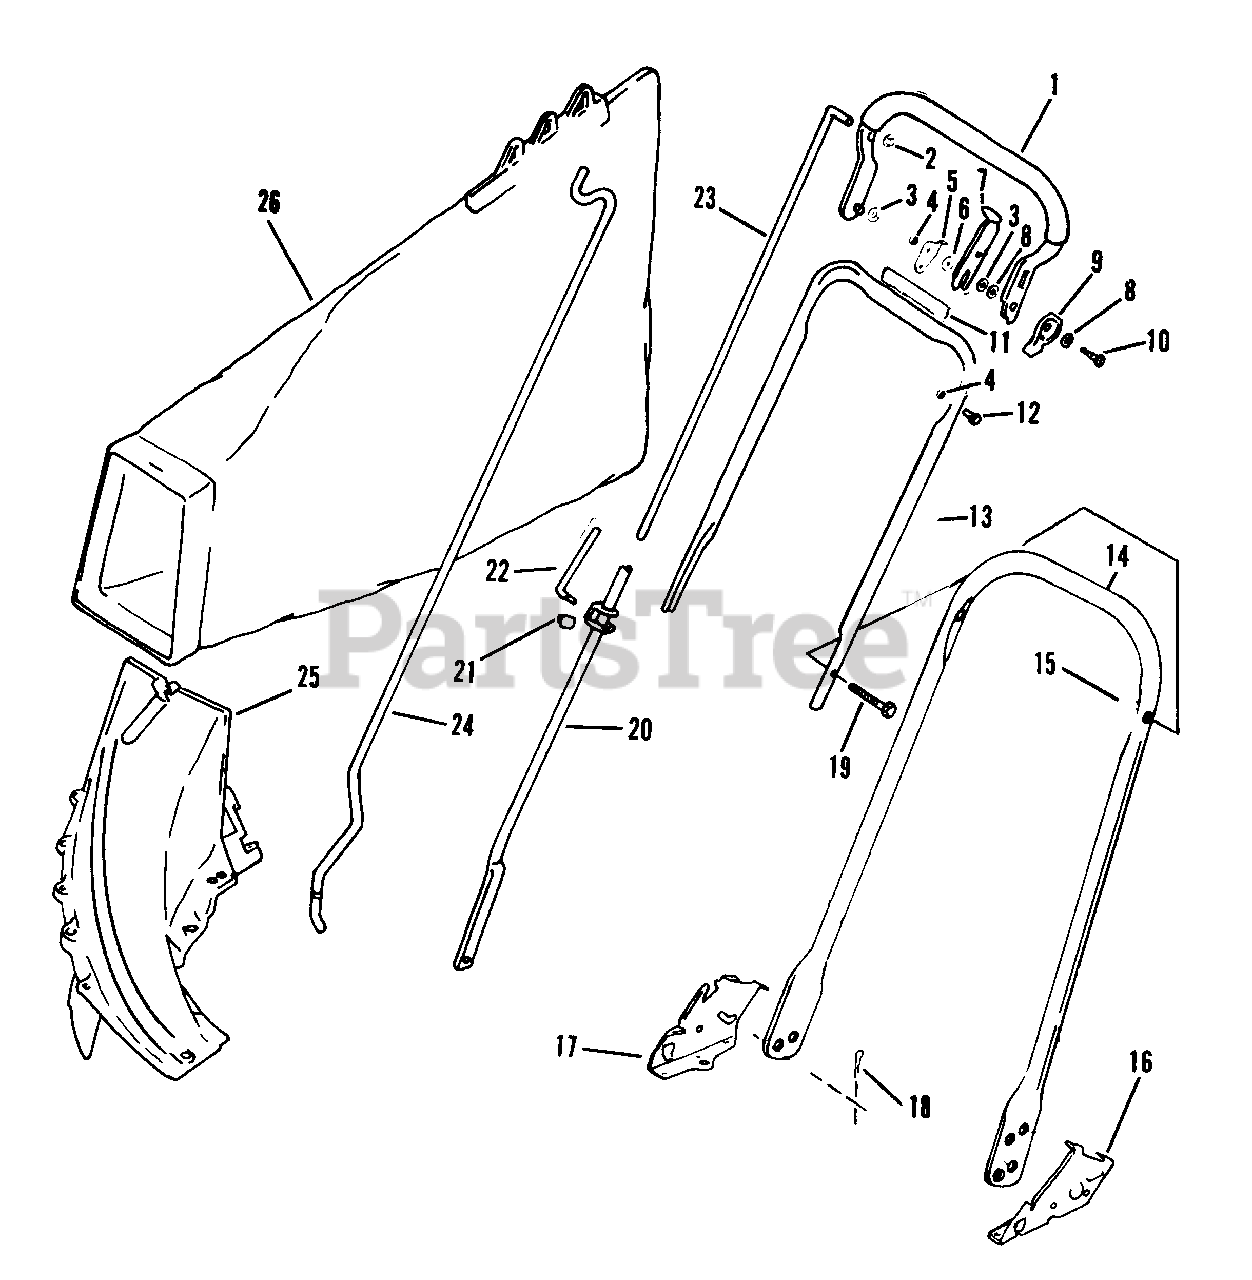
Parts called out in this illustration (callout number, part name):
1	Handle & Grip Assembly
2	Nut
3	Washer
4	Nut-Lock
5	Stop-Handle
6	Washer
7	Lever-Lockout
8	Washer
9	Guard-Lever
10	Bolt-Shoulder
11	Decal
12	Screw-Stop
13	Handle-Center
14	Handle Section-Bottom
15	Nut-Lock
16	Bracket-Handle L.H.
17	Bracket-Handle R.H.
18	Hair Pin
19	Bolt
20	Control Lever Assembly
21	Nut
22	Screw
23	Control Rod
24	Rod-Grass Bag
25	Chute Assembly
26	Bag Assembly
